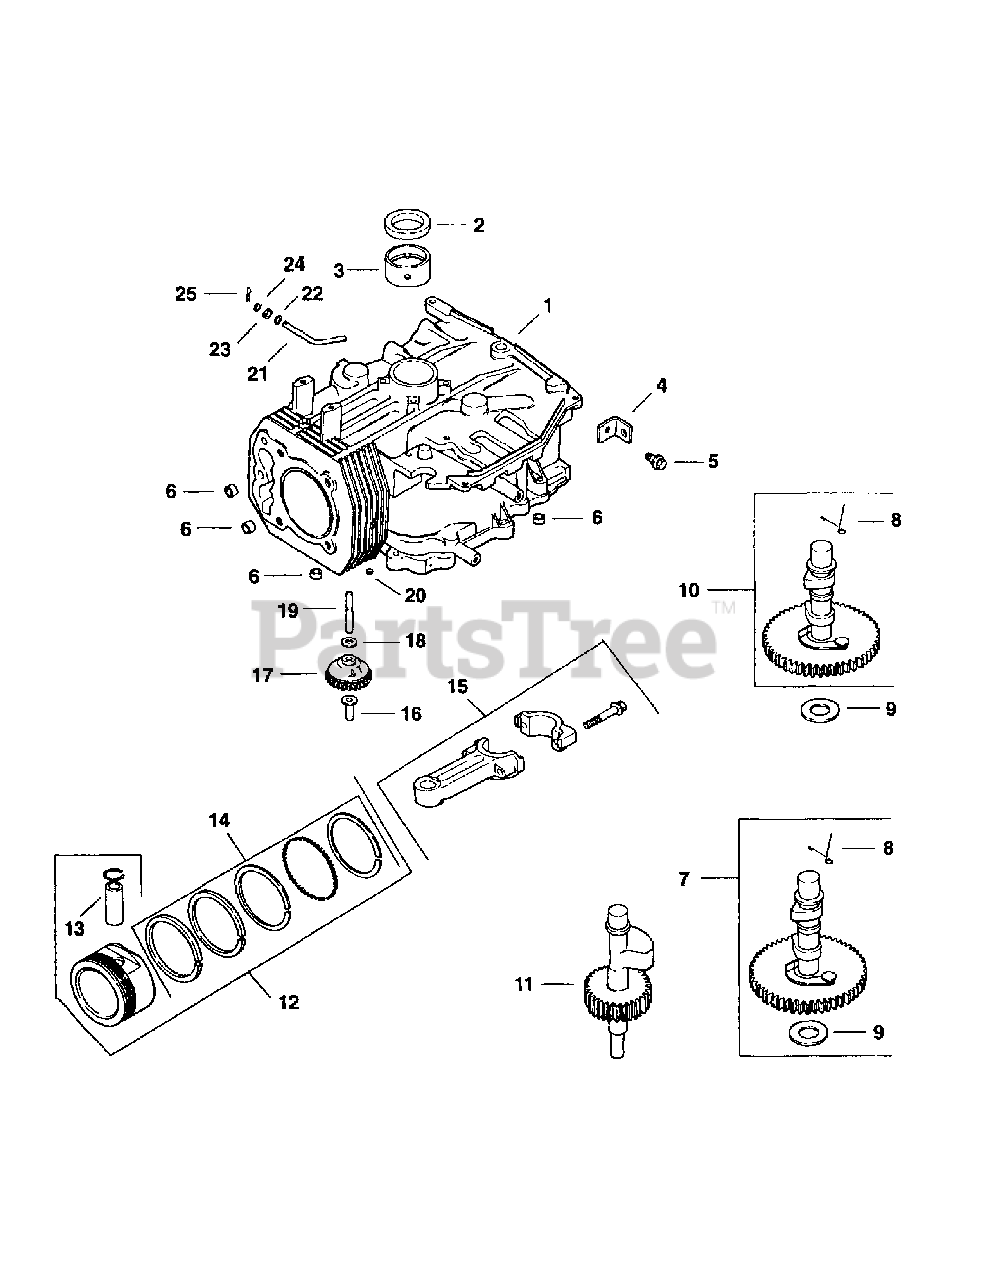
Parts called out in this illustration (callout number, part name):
1	Crankcase
2	Seal, Crankshaft
3	Bearing, Crankshaft (Std.)
3	Bearing, Crankshaft (.25)
3	Bearing, Crankshaft (.50)
4	Strap, Lifting
5	Screw, Lifting Strap M8 x 1.25 x 25
6	Dowel, Locating
7	Kit, Camshaft
8	Spring, Actuating (ACR)
9	Shim, Camshaft (A.R.) (White)
9	Shim, Camshaft (A.R.) (Blue)
9	Shim, Camshaft (A.R.) (Green)
9	Shim, Camshaft (A.R.) (Yellow)
9	Shim, Camshaft (A.R.) (Red)
9	Shim, Camshaft (A.R.) (Gray)
9	Shim, Camshaft (A.R.) (Black)
11	Shaft, Balance
12	Piston w/Ring Set (Std.)
12	Piston w/Ring Set (.25)
12	Piston w/Ring Set (.50)
13	Retainer, Piston Pin
14	Ring Set (Std.)
14	Ring Set (.25)
14	Ring Set (.50)
15	Connecting Rod (Std.)
15	Connecting Rod (.25)
16	Pin, Governor Regulating
17	Gear, Governor
18	Washer, Governor Gear Thrust
19	Shaft, Governor Gear
20	Plug, Cup
21	Governor Cross Shaft Kit
22	Washer, Plain 1/4"
23	Seal, Governor Cross Shaft
24	Washer, Governor Shaft
25	Pin, Governor Hitch
